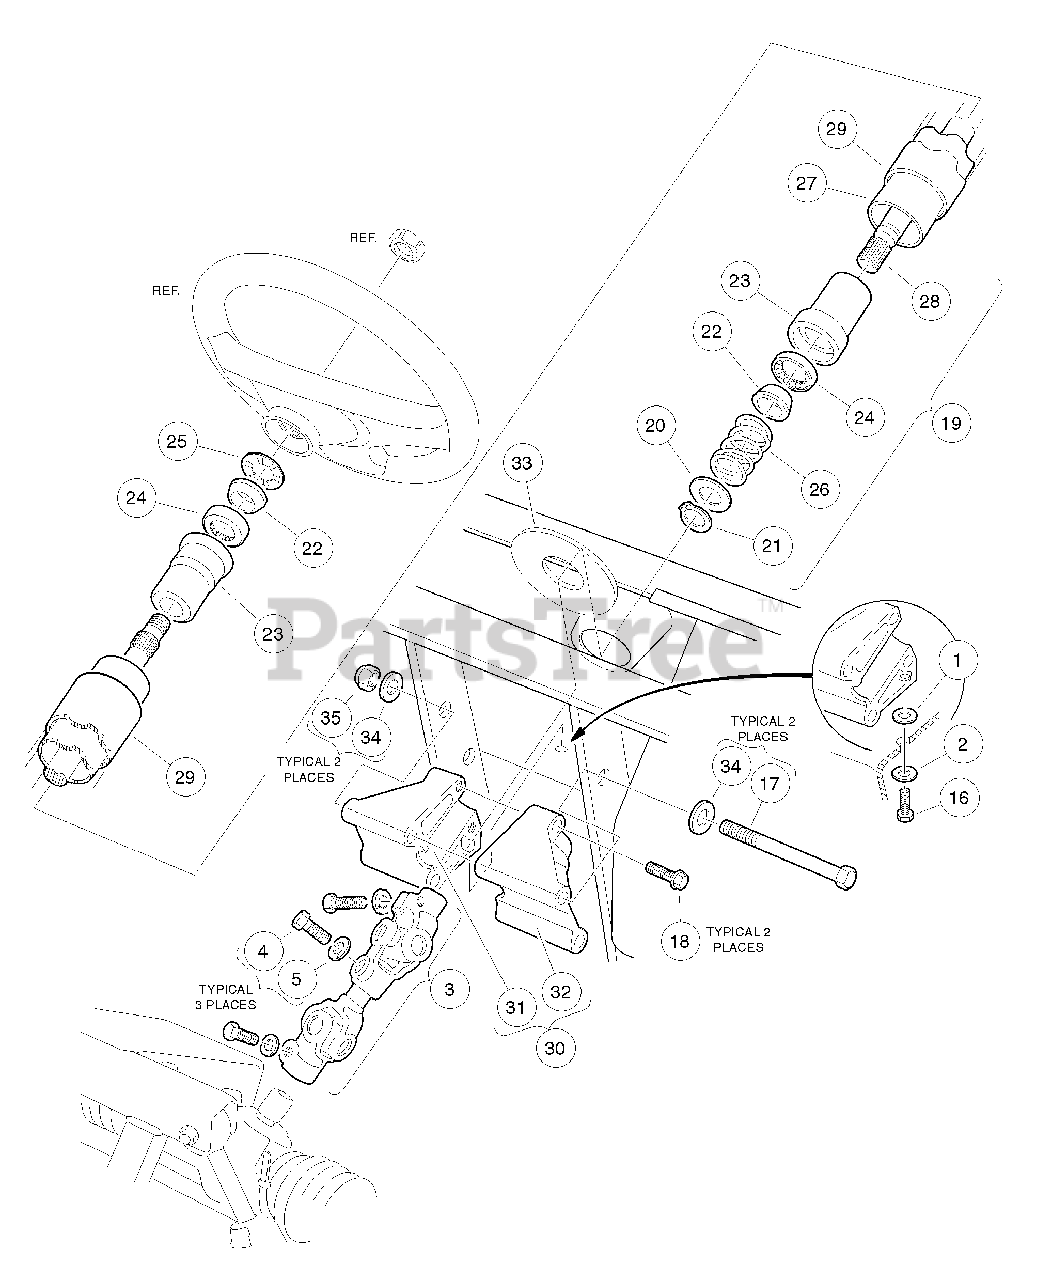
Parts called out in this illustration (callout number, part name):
1	Washer, 5/16 Type B Flat
2	Washer, 5/16 Flat
3	Intermediate Steering Shaft
4	Bolt, Hex-Head, 8mm X 1.25 - 30
5	Lockwasher, 5/16 Split
7	Dust Cover
8	Ring, 0.579 Internal Retaining
9	Wedge, Molded
10	Seat, Plastic Bearing
11	Seal, Bearing
12	Spacer, Shaft
13	Bearing, Ball
14	Ring, Retaining
15	Spring, Steering Shaft
16	Screw, 5/16-18 X 0.75 Thread-Forming
17	Screw, 3/8-16 X 7.00 Hex Cap
18	Screw, 5/16-18 Thrd Forming
19	Steering Shaft Assembly
20	Washer, 0.675 ID X 1.19 OD
21	Ring, 0.579 Internal Retaining
22	Wedge, Molded
23	Seat, Plastic Bearing
24	Bearing, Ball
25	Ring, Retaining
26	Spring, Steering Shaft
27	Column, Aluminum Steering
28	Shaft Steering Column
29	Tube Cover, Steering Column
30	Kit, Steering Column Mounting Bracket
31	Bracket, RH Steering Column Mount
32	Bracket, LH Steering column mount
33	Boot, Steering Column Round
34	Washer, 3/8 Type A Flat
35	Locknut, 3/8-16 Hex
